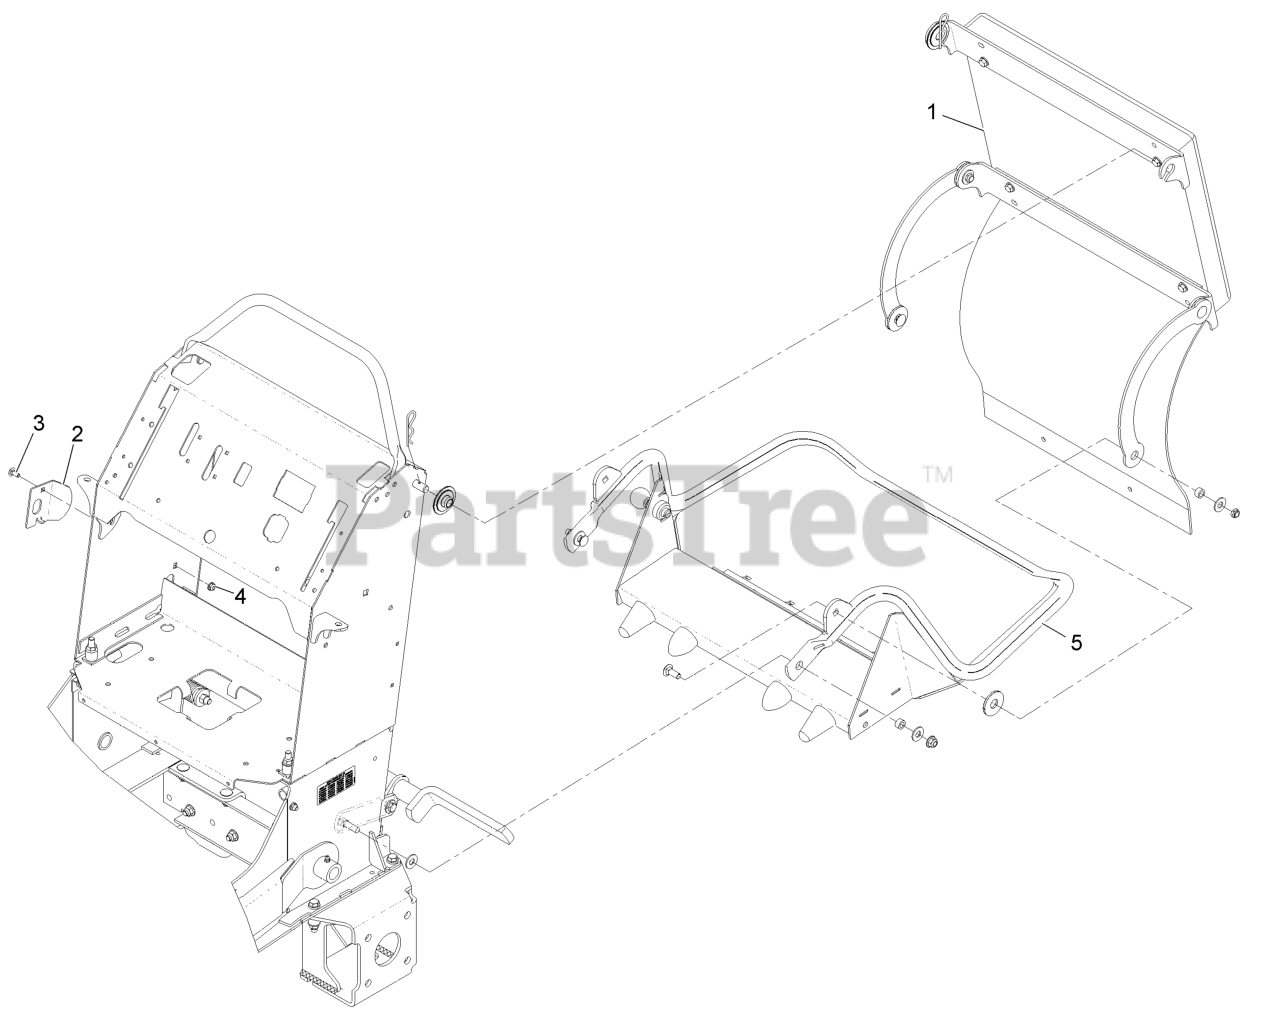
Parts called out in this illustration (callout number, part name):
2	PLATE-STRIKER
3	SCREW-CARR
5	ASM,PLATFORM
